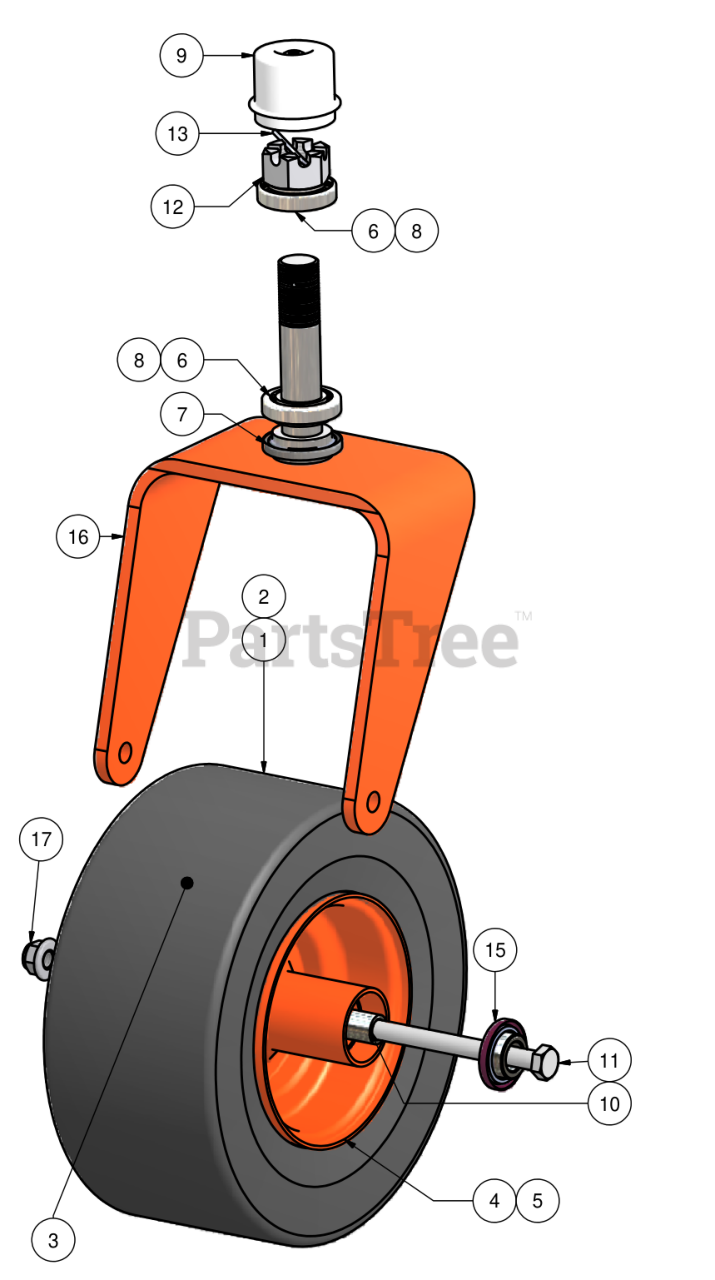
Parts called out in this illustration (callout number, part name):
1	13 x 6.5- 6" Tire and Wheel Assembly
2	13 x 6.5-6" Assembly for 36" ZT
3	13 x 6.5-6" Tire
4	6" Wheel ONLY
5	6" Silver Wheel for
9	Dust Cover
10	Wheel Spacer
11	1/2" x 9" Bolt
12	1" Fine Threaded Castle Nut
13	1/8" x 2 1/4" Cotter #8
15	Wheel Bearing
16	Front Fork with Spindle
17	1/2" Flange Lock
